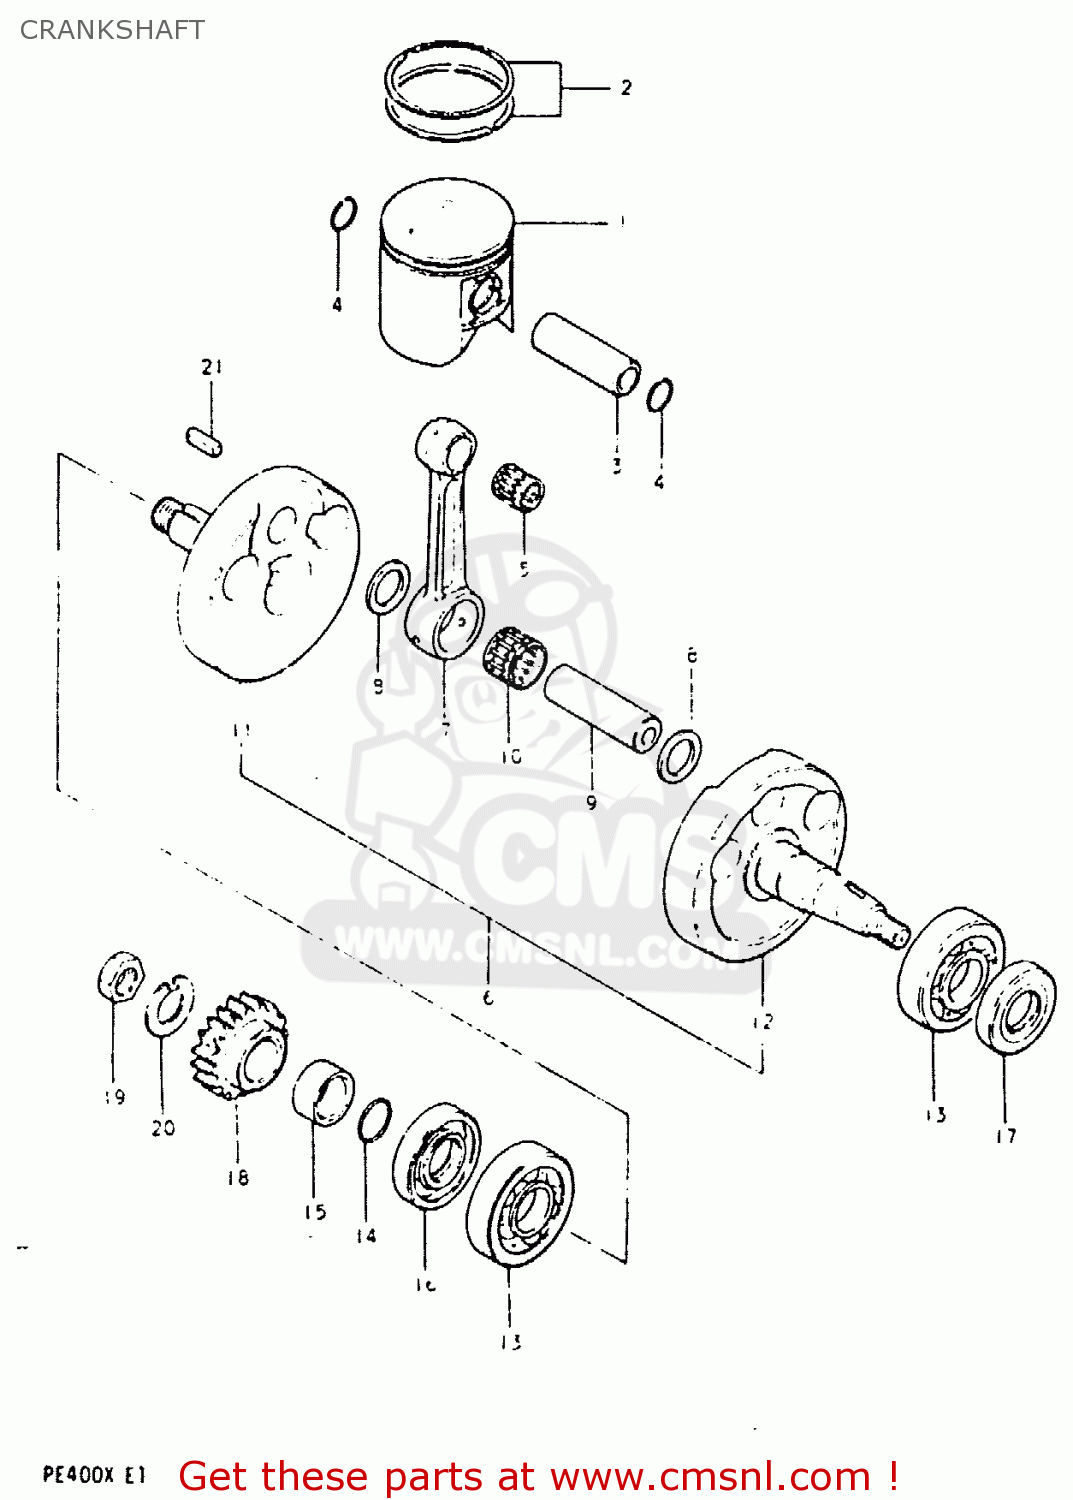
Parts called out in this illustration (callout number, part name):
1	PISTON (85.00MM)
2	RING SET,PISTON
3	PISTON PIN
4	CIRCLIP
5	BEARING(20X25X22)
6	CRANKSHAFT ASSEMBLY
7	ROD,CONNECTING
8	WASHER(24X29X2)
9	PIN,CRANK
10	BEARING
11	CRANKSHAFT
12	CRANKSHAFT,LEFT
13	BEARING
14	O RING(D:2.4,ID:21.8)
15	SPACER (22X37X12.5)
16	SEAL,OIL(37X62X9)
17	SEAL,OIL(24X50X9)
18	GEAR,PRIMARY DRIVE
19	NUT
20	WASHER
21	KEY
